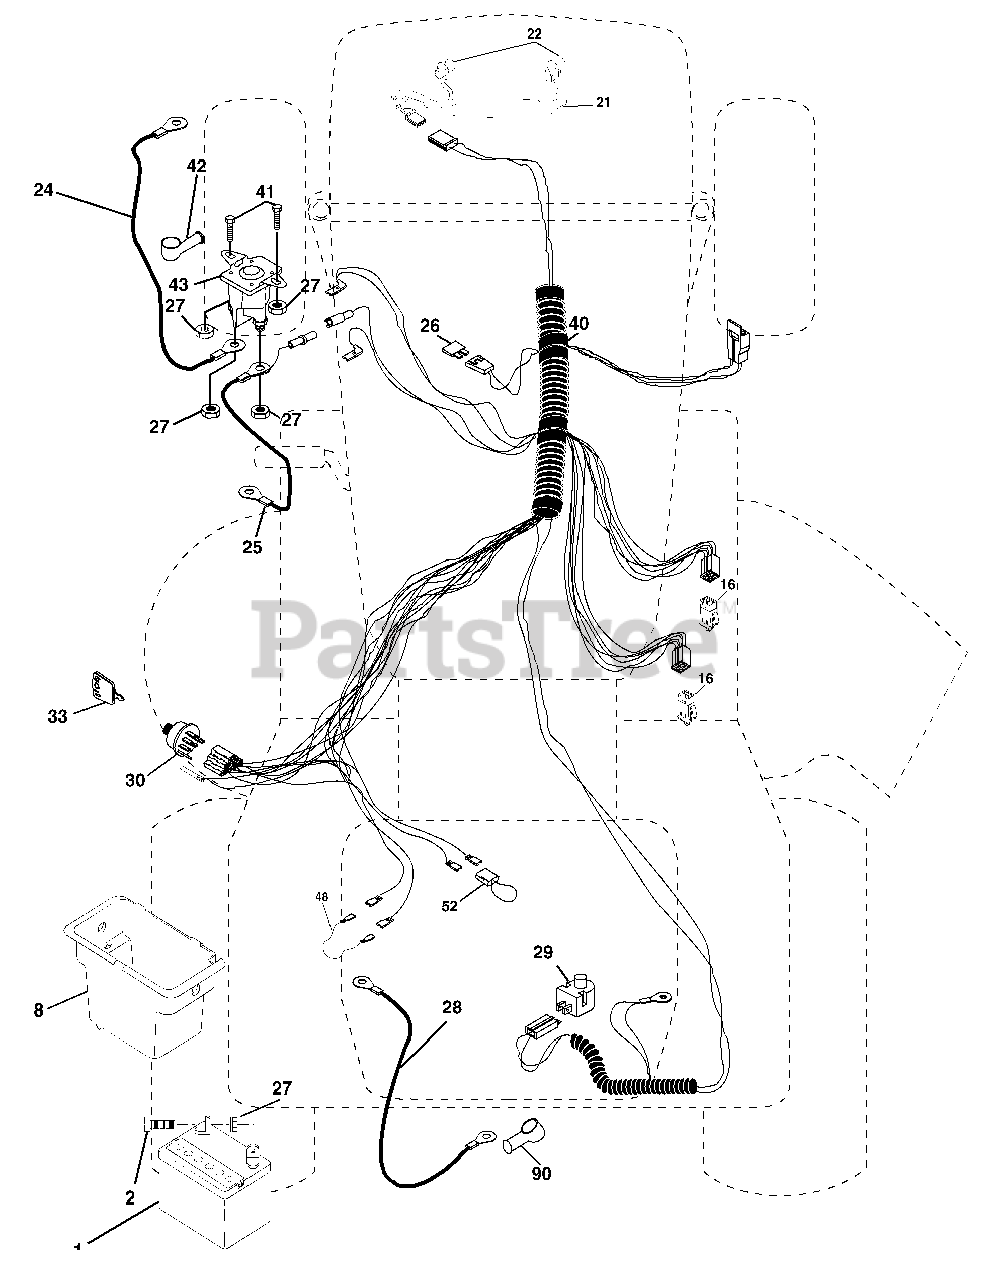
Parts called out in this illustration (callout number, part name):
1	Battery
2	Bolt Hex Hd 1/4-20unc X 3/4
8	Box Battery
16	Switch Interlock
21	Harness Asm Light W/4152j
22	Bulb Light #1156
24	Cable Battery 6 Ga 11" red
25	Cable Battery
26	Fuse 20 AMP
27	Nut Keps Hex 1/4-20 Unc
28	Cable Ground 6 Ga 12" black
29	Switch Plunger Nc Gray
30	Switch Ign
33	Key Ign
40	Harness Ign
41	Bolt Blk Fin Hex 1/4-20
42	Cover Terminal Red
43	Solenoid
48	Adapter Ammeter
52	Protection Wire Loop
90	Cover Terminal Battery
